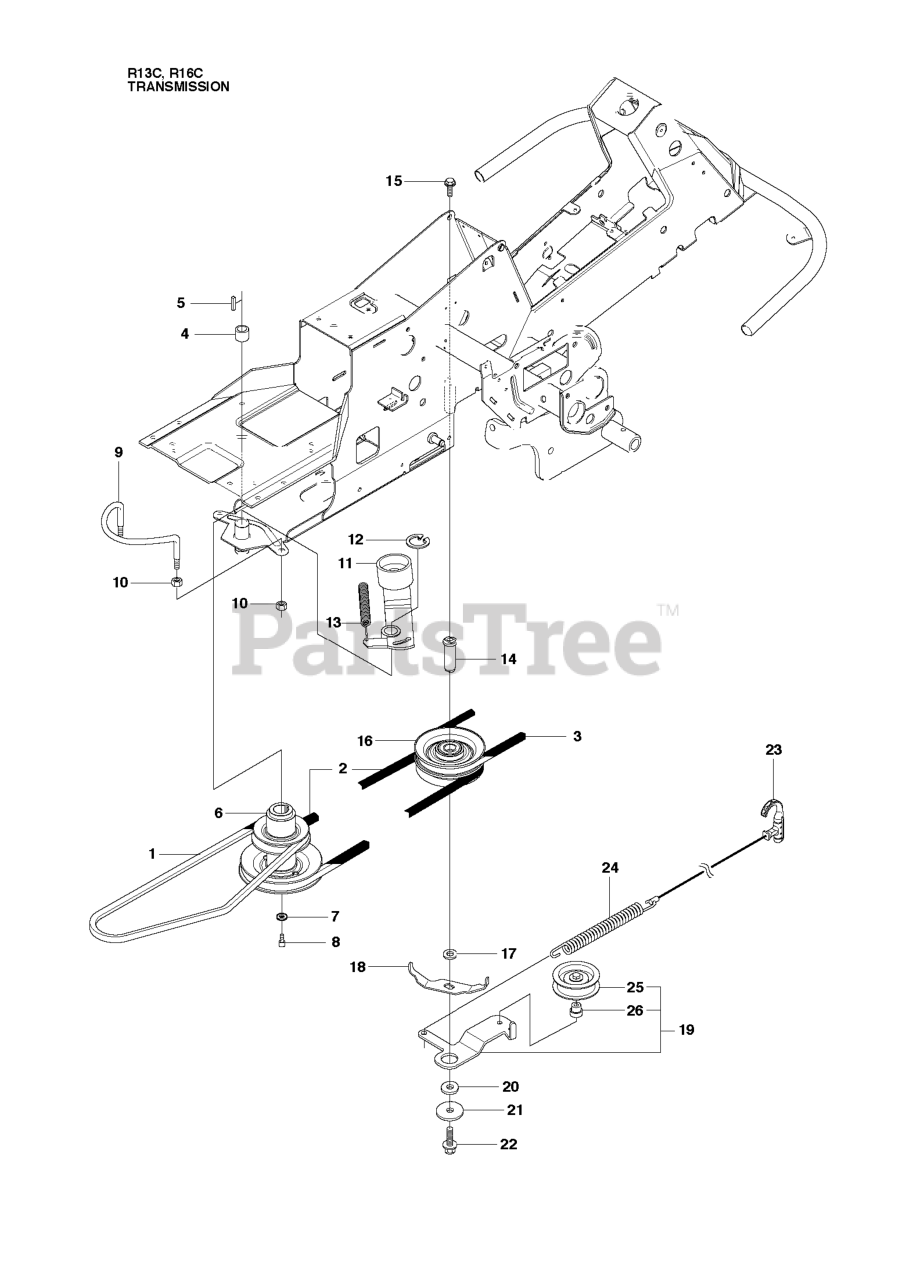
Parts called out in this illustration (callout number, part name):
9	BELT GUIDE
10	NUT
12	RETAINING RING SGA 25
14	SHAFT
18	BELT GUIDE
19	BELT TENSIONER ASSY
22	BOLT
25	PULLEY
